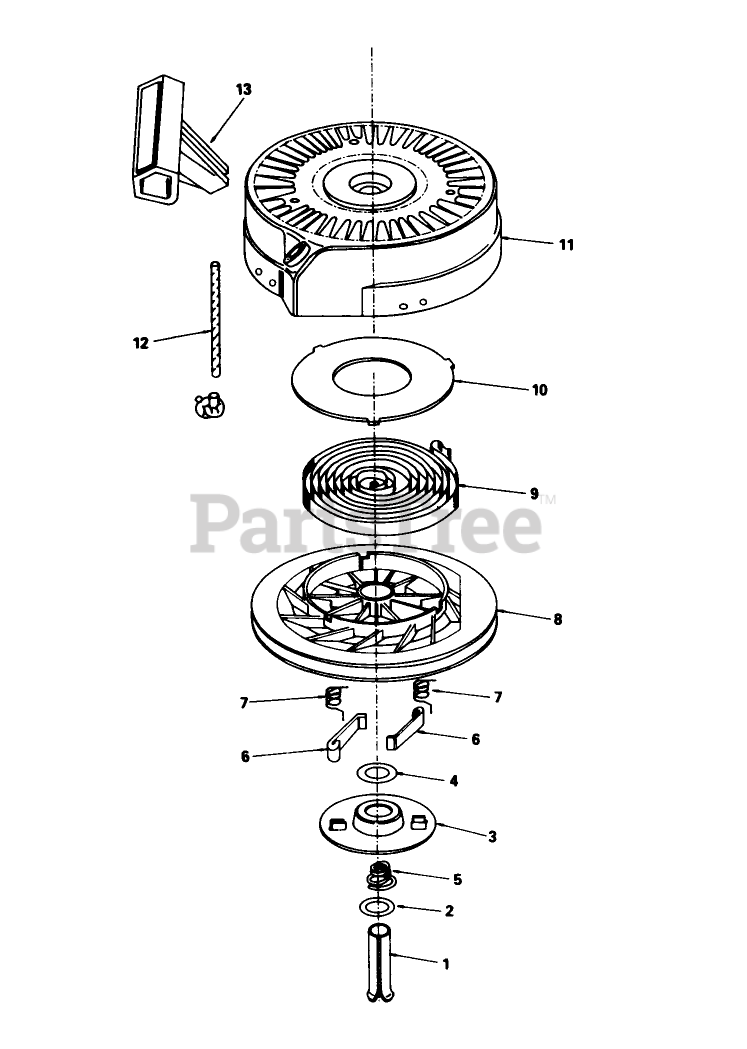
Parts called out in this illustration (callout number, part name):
1	Pin Spring
3	Retainer
5	Brake Spring
6	Dog-Starter
7	Spring-Dog
8	Pulley
9	Rewind Spring
10	Cover-Spring
11	Housing-Starter
12	Rope-Starter (98 cut to length)
13	Handle-Starter
